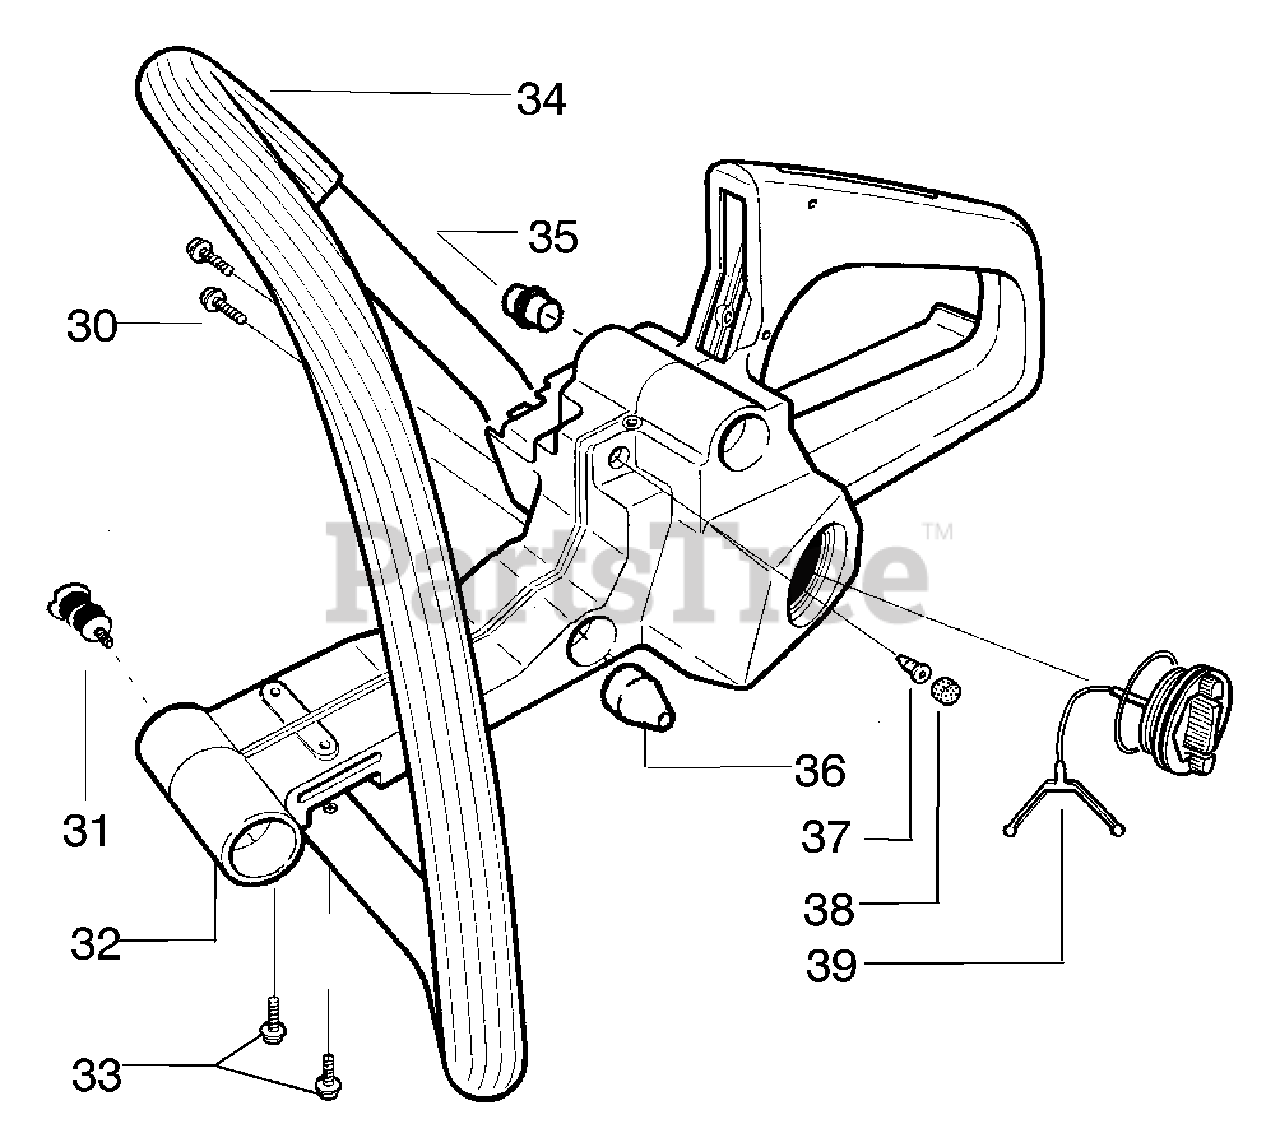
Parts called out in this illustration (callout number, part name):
31	Element - AV Isolator
32	Assy. -Tank/Handle
34	Handle-Front
35	Isolator-Front Handle
37	Valve - Check
38	Plug - Vent
39	Kit-Assy. Fuel Cap
